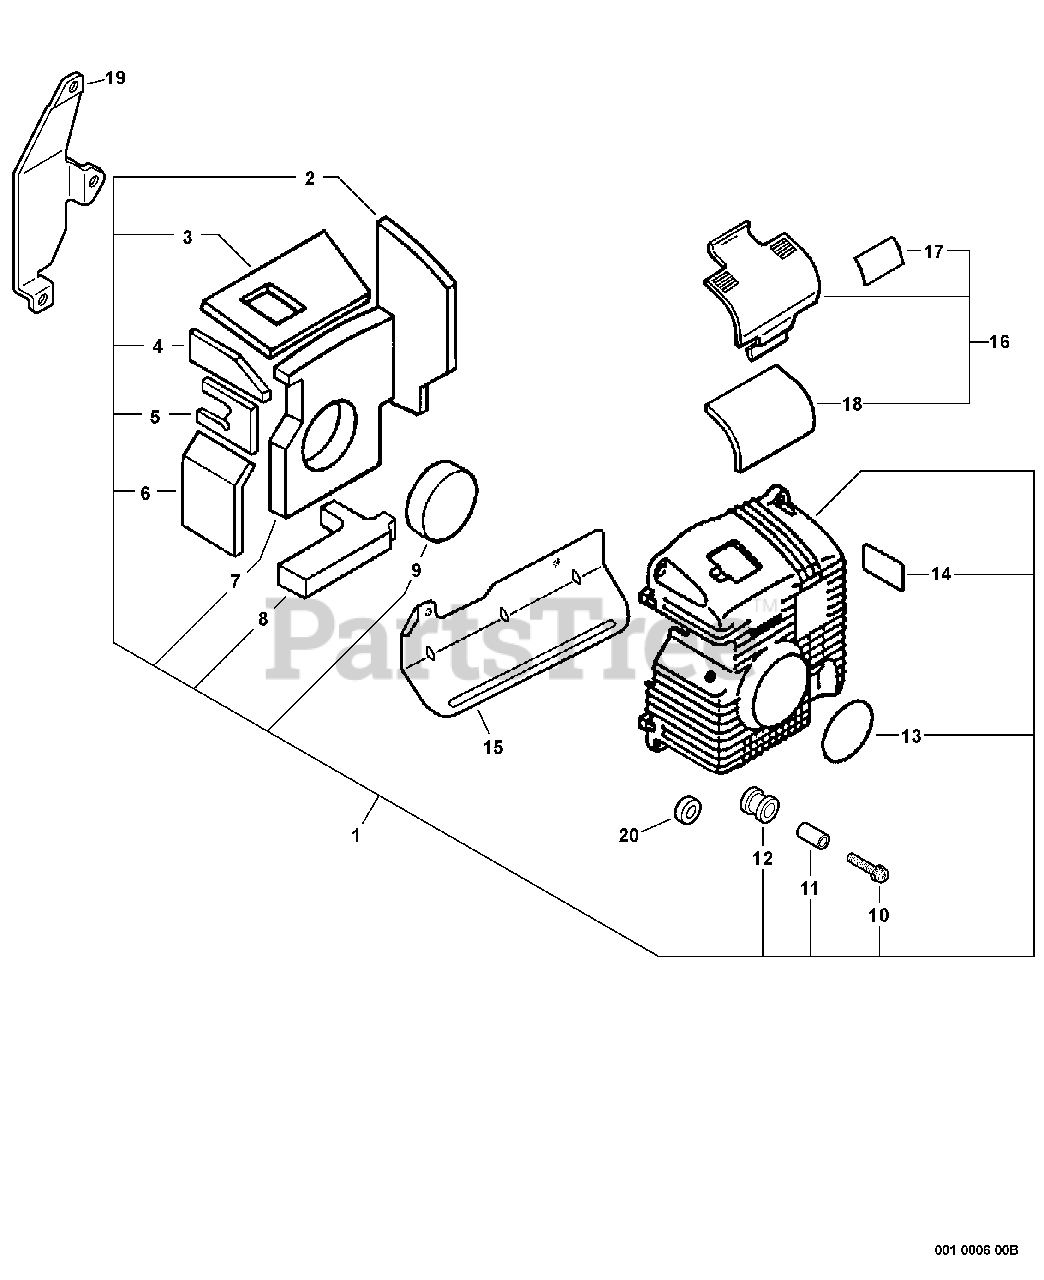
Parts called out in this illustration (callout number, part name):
1	ENGINE COVER KIT
2	PAD, FOAM - RIGHT
3	PAD, FOAM - TOP
4	PAD, FOAM - LEFT TOP
5	PAD, FOAM - LEFT CENTER
6	PAD, FOAM - LEFT BOTTOM
7	PAD, FOAM - REAR
8	PAD, FOAM - BOTTOM
9	PAD, FOAM - CENTER REAR
10	SCREW 5×25
13	LABEL - ECHO
14	LABEL, CAUTION - HOT
15	DEFLECTOR, HEAT
16	SPARK PLUG COVER ASSY
17	LABEL, CAUTION
18	PAD, FOAM - SPARK PLUG CAP
19	INSULATOR, MUFFLER
20	CUSHION
